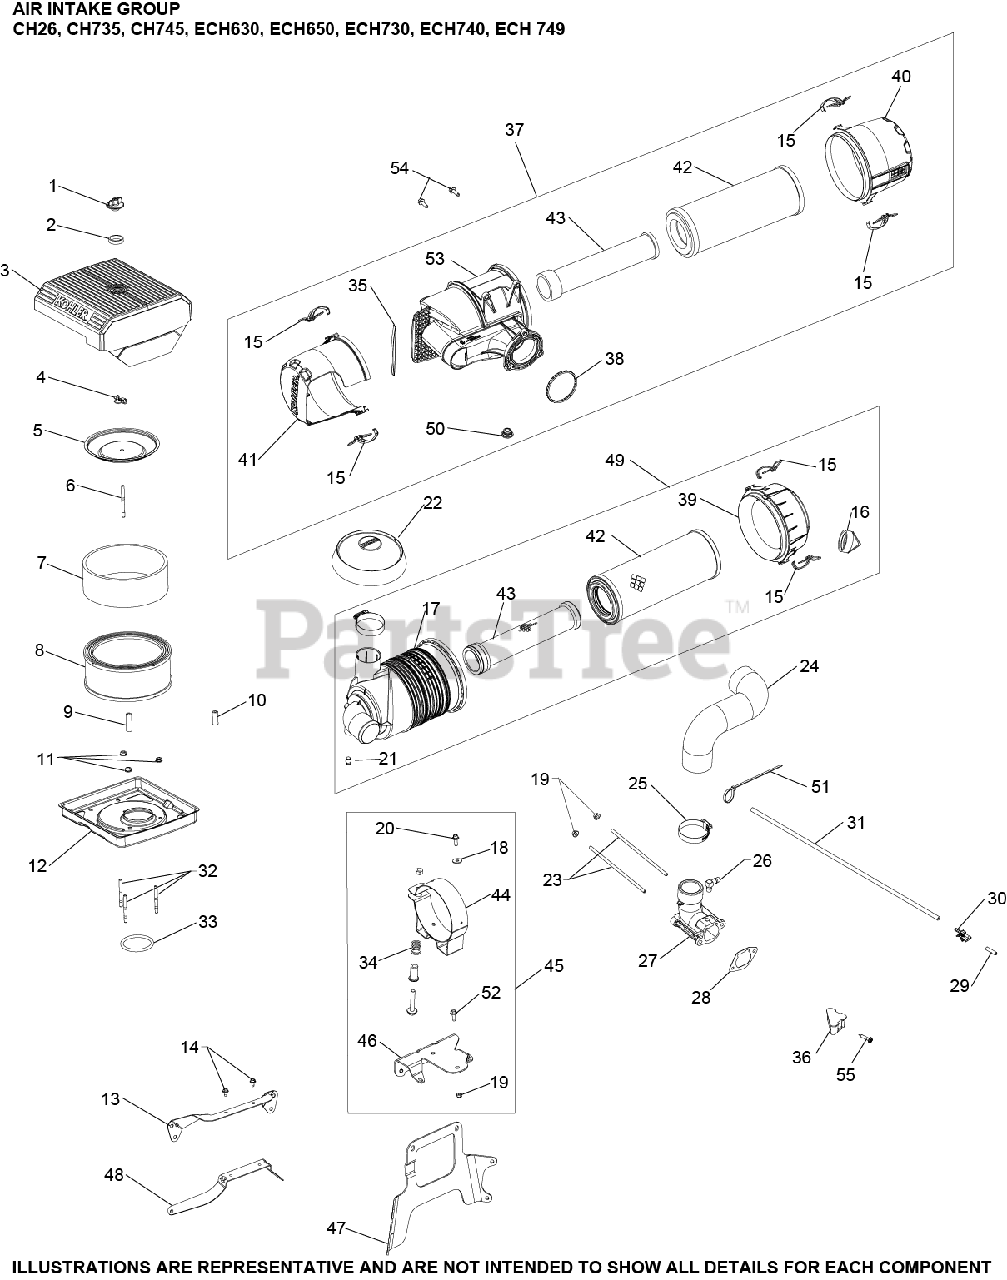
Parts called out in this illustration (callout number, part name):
1	KNOB, COVER
3	COVER, AIR CLEANER
4	NUT, WING
5	COVER, INNER AIR CLEANER
7	ELEMENT, PRECLEANER (LOW)
8	ELEMENT, AIR CLEANER - Also available Retail Packaged 47 883 03-S1 Air Filter Kit
12	BASE, AIR CLEANER
13	BRACKET, AIR CLEANER BASE
14	SCREW, THREAD FORMING
32	STUD, LOW PROFILE A/C
33	O-RING, AIR CLEANER BASE
